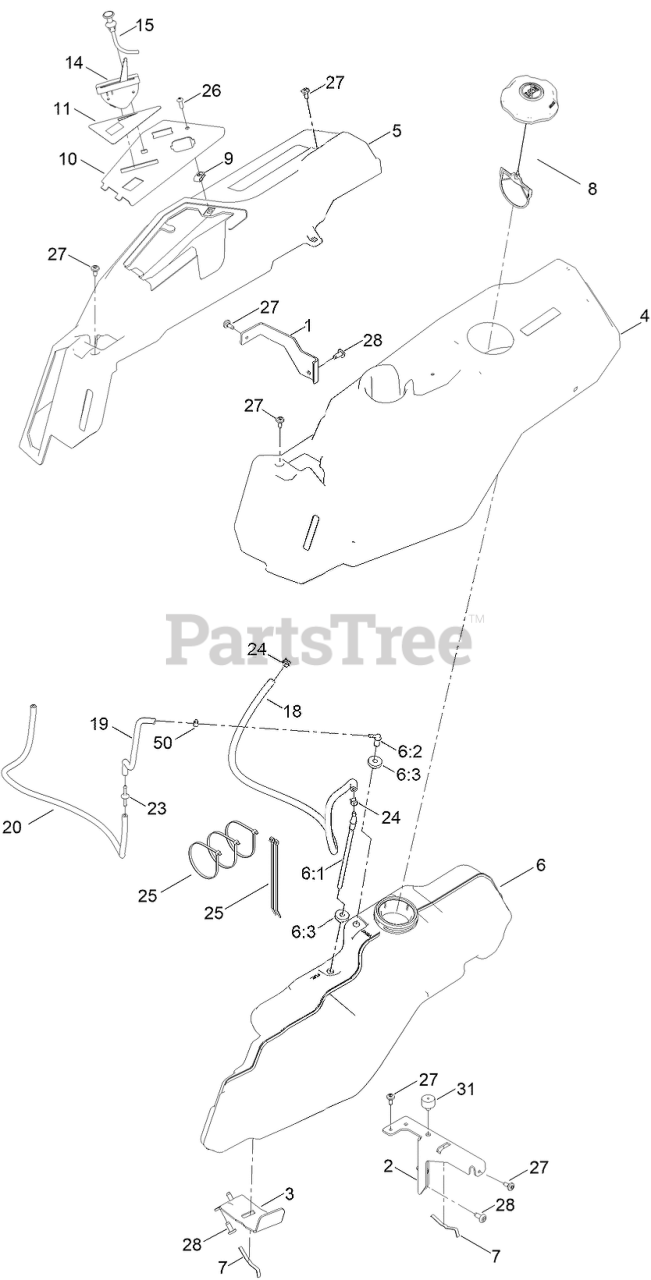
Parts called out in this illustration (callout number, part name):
1	SUPPORT-POD, RH
2	SUPPORT-POD, LH
3	SUPPORT-TANK, FUEL
4	POD-LH
5	POD-RH
6	TANK-FUEL ASM
6:1	CONNECTOR-ELBOW, 90 DEG
6:2	FITTING-ELBOW 90
6:3	BUSHING
7	SPRING
8	CAP-FUEL, RATCHETING
10	PANEL - CONTROL
11	DECAL-PANEL CONTROL
14	CABLE-THROTTLE
15	CABLE-CHOKE
18	HOSE-FUEL
19	HOSE-FUEL
20	HOSE-FUEL
23	ADAPTER ORIFICE
24	CLAMP-HOSE
25	TIE-CABLE
26	SCREW-PRH
27	SCREW-SHOULDER
31	BUMPER-GROMMET
50	CLAMP-HOSE
